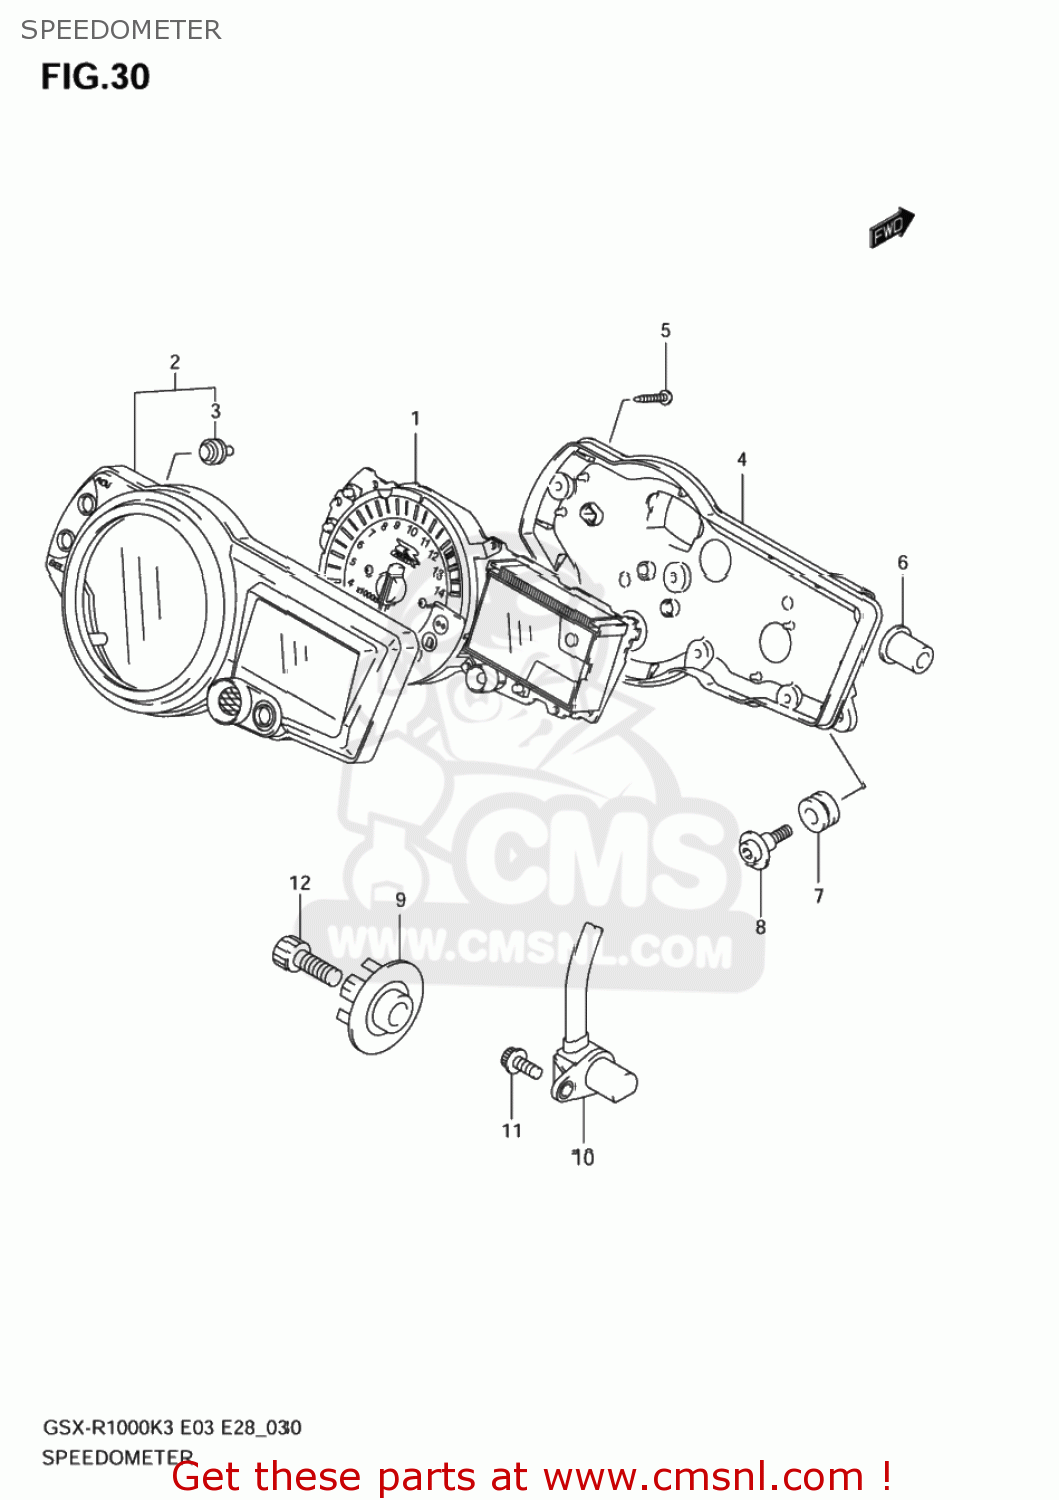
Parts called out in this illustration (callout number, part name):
1	SPEED & TACHOMETER ASSY
2	CASE,SPEEDOMETER UPR
3	SWITCH,LEVER
4	CASE,SPEEDOMETER LWR
5	SCREW(3X16)
6	CUSHION
7	CUSHION,METER
8	SCREW,SPEEDOMETER
9	ROTOR,SPEED
10	SENSOR,SPEED
11	BOLT
12	BOLT
